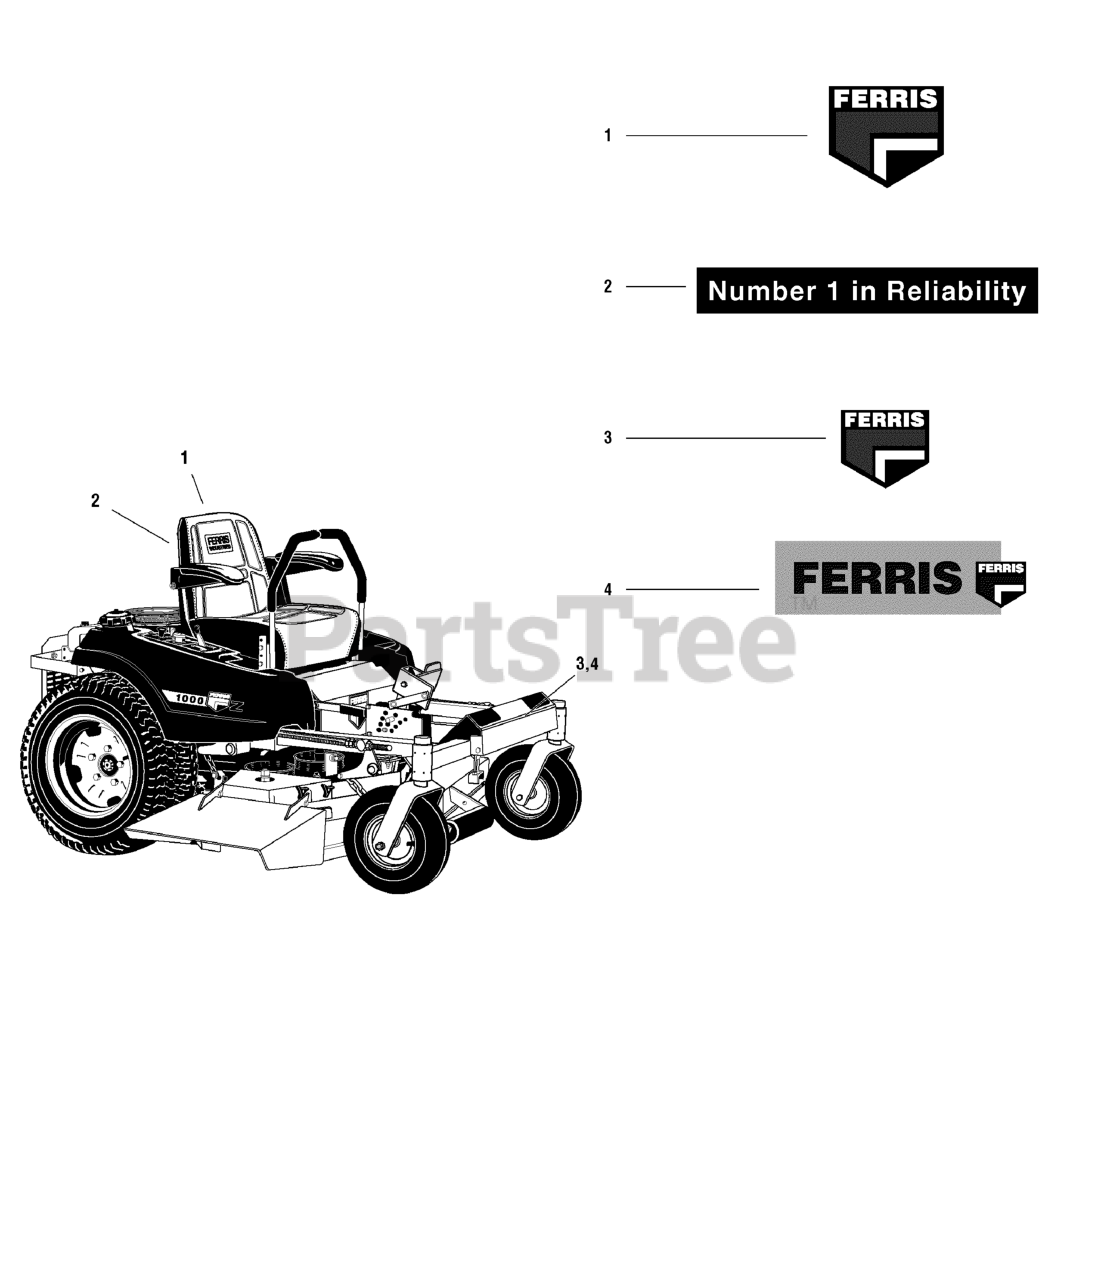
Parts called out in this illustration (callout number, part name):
1	DECAL, Ferris Logo, 6-3/8"
2	DECAL, Number One In Reliability
3	DECAL, Ferris Logo, 5"
4	DECAL, FERRIS TEXT & LOGO
